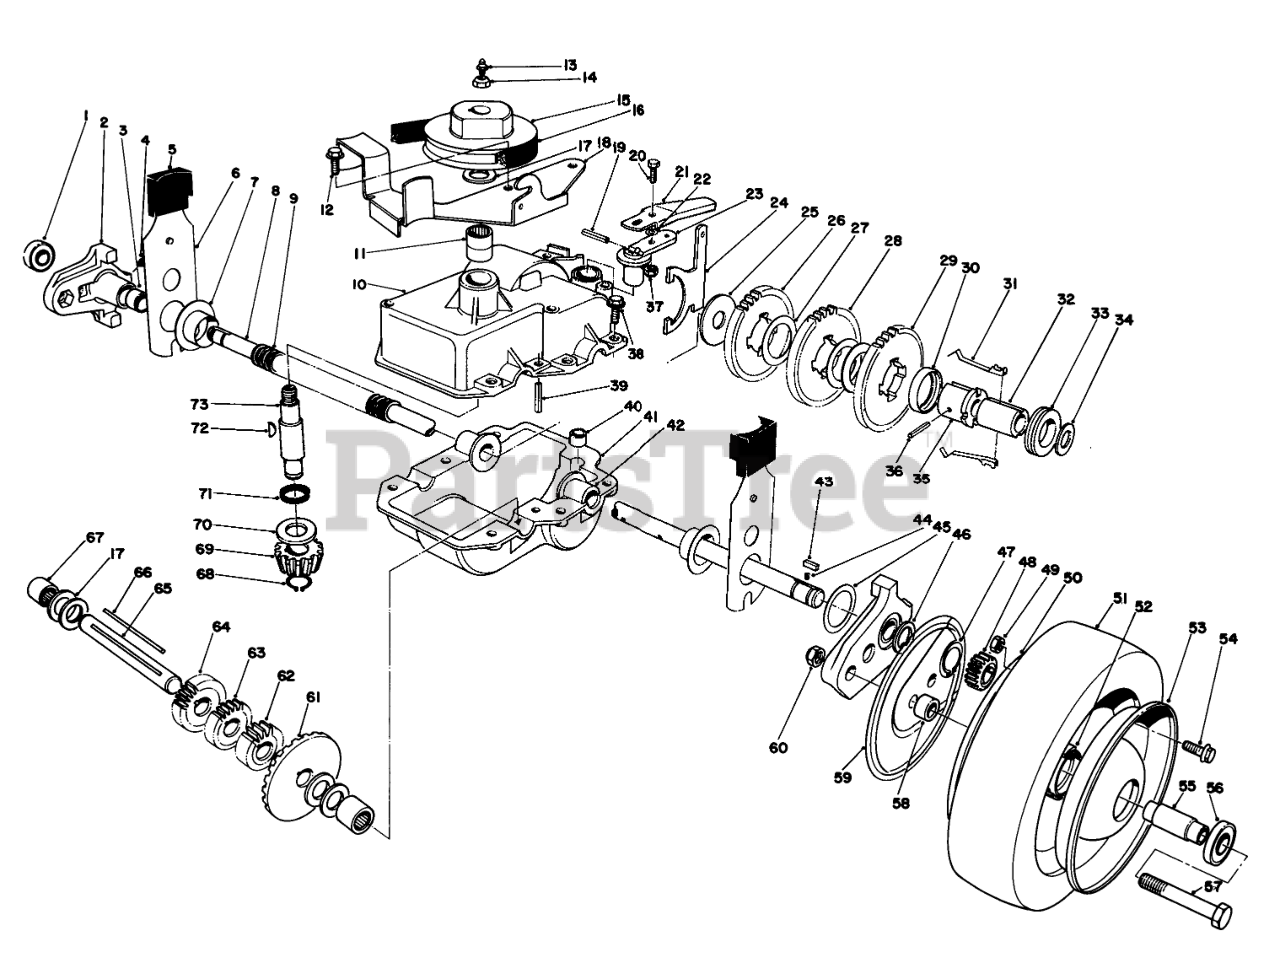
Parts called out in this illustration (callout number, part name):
1	BEARING-WHEEL
2	Pivot Arm Assembly (Incl. Ref. #1 8 3-4)
3	BUSHING
4	FITTING-GREASE
5	KNOB-ARM
6	Spring Arm
7	CAP-END
8	Output Shaft
9	CONDUIT-CONVOLUTED, SPLIT
10	Upper Case Assembly (Incl. Ref. #11 8 71)
11	BEARING-NEEDLE
12	SCREW
13	FITTING-GREASE
14	NUT-HEX
15	PULLEY
16	V-BELT
17	WASHER-THRUST
18	Belt Guide Bracket
19	PIN-COIL
21	SHIFT LEVER COVER
22	WASHER-FLAT
23	LEVER-SHIFT
24	Shift Yoke
25	WASHER
26	GEAR-38T
27	WASHER
28	GEAR-42T
30	RETAINER-KEY
31	KEY-SHIFT
32	SLEEVE
33	COLLAR-SHIFT
34	WASHER-PLAIN
35	SLEEVE-GEAR
36	PIN-GROOVE
37	NUT-LOCK, NI
38	SCREW-HWHTF
39	ROLL PIN 3/16 X 1 IN
40	BUSHING-YOKE
41	Case-Lower
42	BUSHING
43	KEY RECTANGULAR
44	SPRING-COMPRESSION
45	WASHER
46	KEYED WASHER
47	RING-RETAINING
48	GEAR-PINION
49	NUT-LOCK, NI
50	Wheel-Inner Half
52	HUB-BEARING
53	Wheel-Half
54	SCREW-HHF
55	SPACER-BEARING
56	BEARING-WHEEL
57	SCREW-HH
58	SPACER-WHEEL
59	WHEEL COVER
60	NUT-LOCK, CONE
61	BEVEL GEAR
62	GEAR-12T
63	GEAR-14T
64	GEAR-18T
65	SHAFT-INTERMEDIATE
67	BEARING-NEEDLE, CLOSED
68	RING-RETAINING
69	PINION-BEVEL
70	WASHER-THRUST
72	KEY-WOODRUFF
73	Shaft Input
